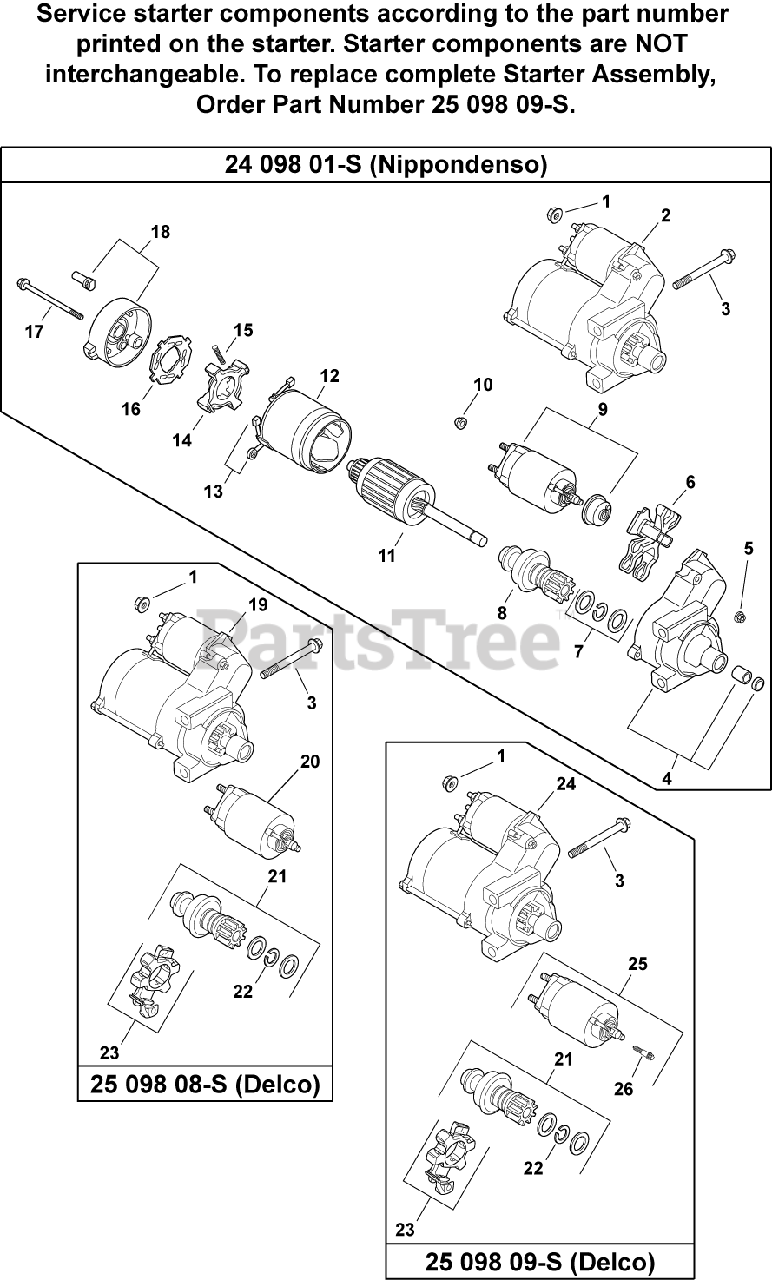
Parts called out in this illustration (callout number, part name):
1	NUT, FLG M8X1.25
3	SCREW, FLG M8X1.25X80
4	DRIVE, END CAP
6	LEVER, DRIVE
7	KIT, STARTER REPAIR
8	DRIVE PINION
11	ARMATURE - (#DSC)
12	FRAME W/BRUSHES - DISCONTINUED
13	BRUSH HOLDER
14	BRUSH & SPRING KIT
15	SPRING, BRUSH
16	INSULATOR
17	THRU BOLT
18	COMMUTATOR, END CAP - DISCONTINUED
19	STARTER, SOLENOID SHIFT-USE 25 098 11-S
21	KIT, STARTER PINION
22	RING, RETAINING
23	KIT, BRUSH HOLDER
24	STARTER, SOLENOID SHIFT-USE 25 098 11-S
25	KIT, SOLENOID
26	SCREW, EXTERNAL TORX HEAD
